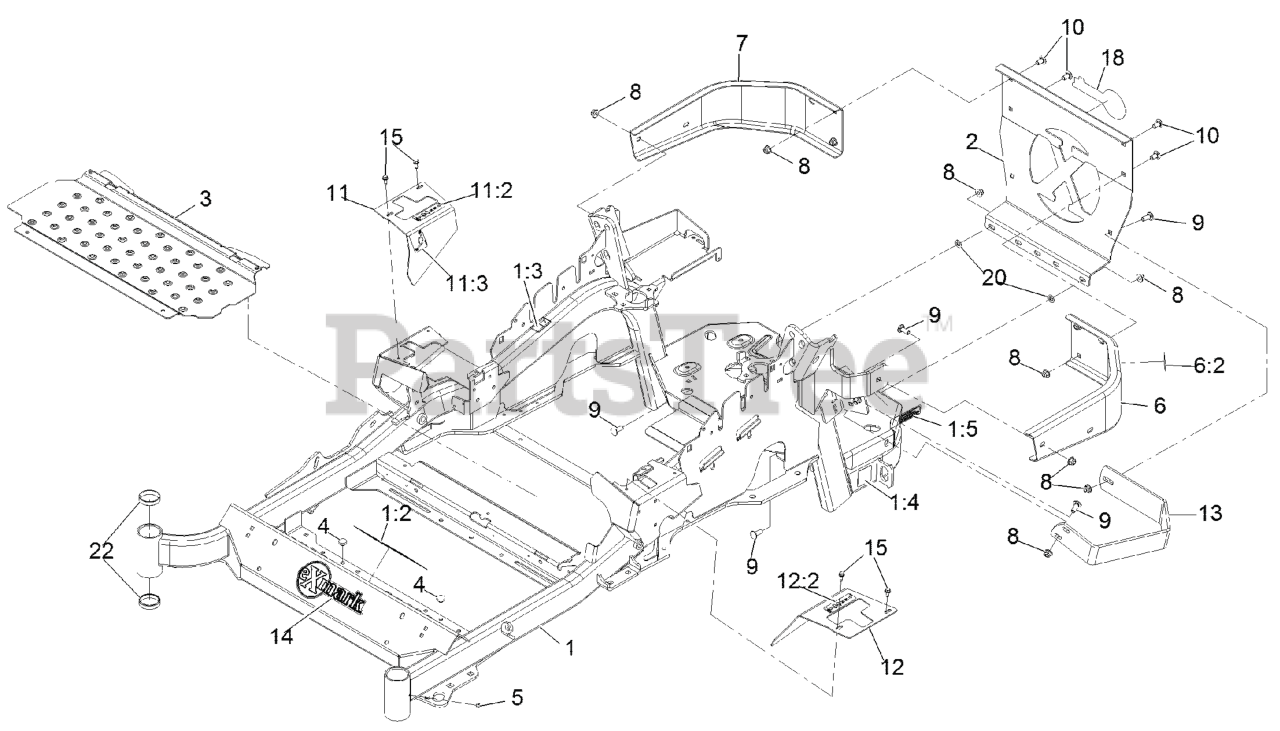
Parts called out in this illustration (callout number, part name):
1	MAINFRAME ASM
1:2	DECAL-DANGER
1:3	DECAL-WARNING
1:4	DECAL-HAZARD, PINCHED FINGER
1:5	DECAL-ARRESTOR, SPARK
2	PLATE,REAR GUARD
6	LH BUMPER ASM
6:2	DECAL-WARNING
7	BUMPER-RH
8	NUT-HF, NI
9	SCREW-CARR
10	SCREW-CARR
11	RH MOTION CONTROL COVER ASM
11:2	DECAL-CONTROL, MOTION
11:3	DECAL-PARK BRAKE, CE
12	LH MOTION CONTROL COVER ASM
12:2	DECAL-CONTROL, MOTION
13	GUARD-MUFFLER
14	DECAL-EXMARK
15	SCREW-HWH
18	DECAL-EXMARK LOGO
20	NUT-PUSH
22	CUP-BEARING
